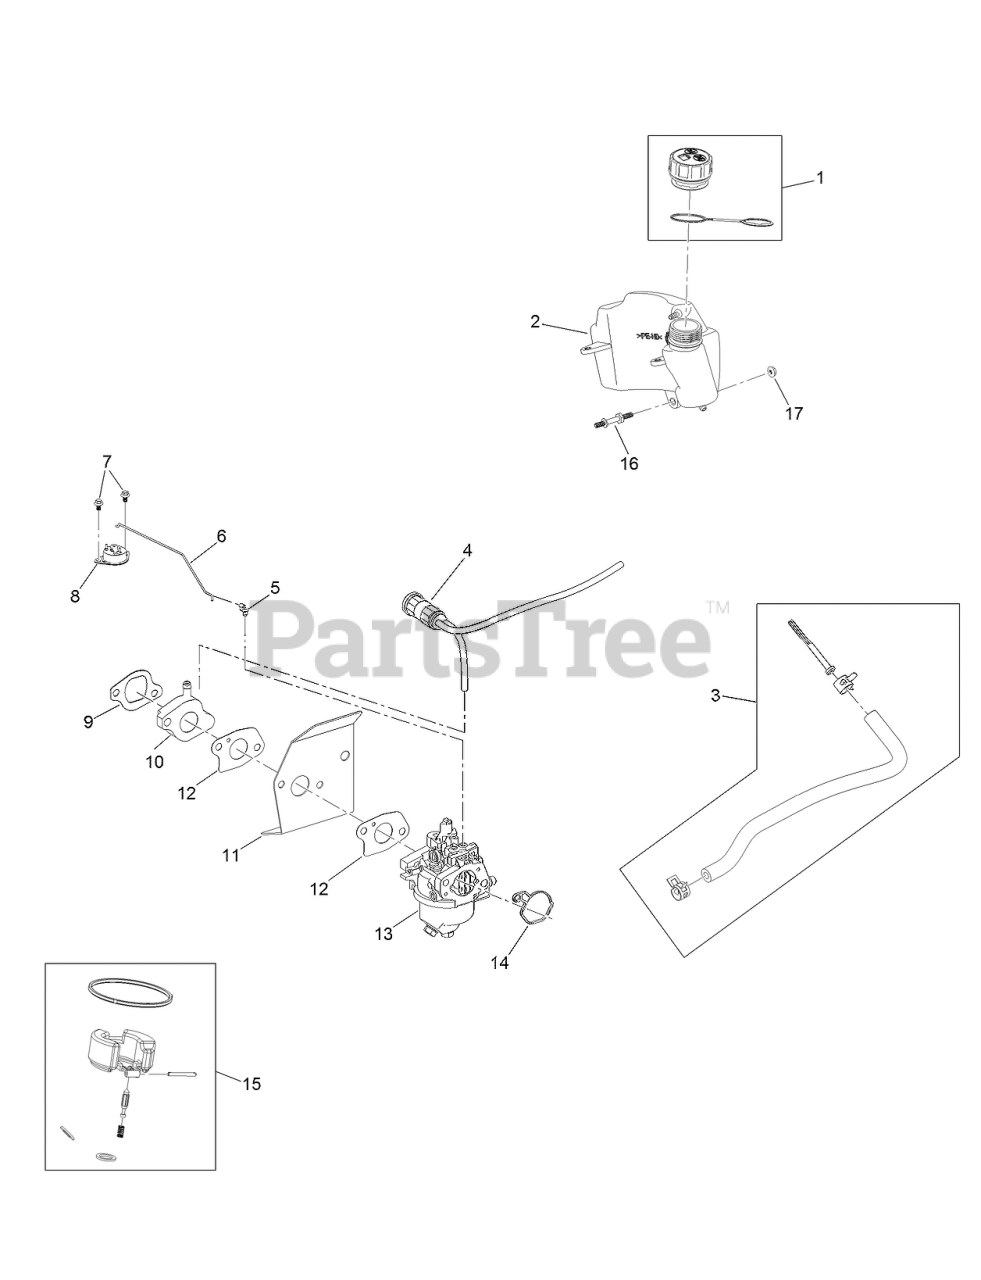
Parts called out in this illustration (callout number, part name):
1	CAP-FUEL, SEALED
2	TANK-FUEL
3	FUEL LINE KIT
4	CANISTER-CARBON, 19 CC
5	LOCK-THROTTLE
6	LINKAGE-CHOKE, THERMAL
7	SCREW-HWHTF
8	CONTROL-THERMAL
9	GASKET-INTAKE
10	SPACER-CARBURETOR
11	INSULATOR-CARBURETOR
12	GASKET-CARBURETOR
13	CARBURETOR
14	GASKET-CARBURETOR
15	INTERNAL CARB SERVICE KIT
16	BOLT-STUD
17	NUT-FLANGE
